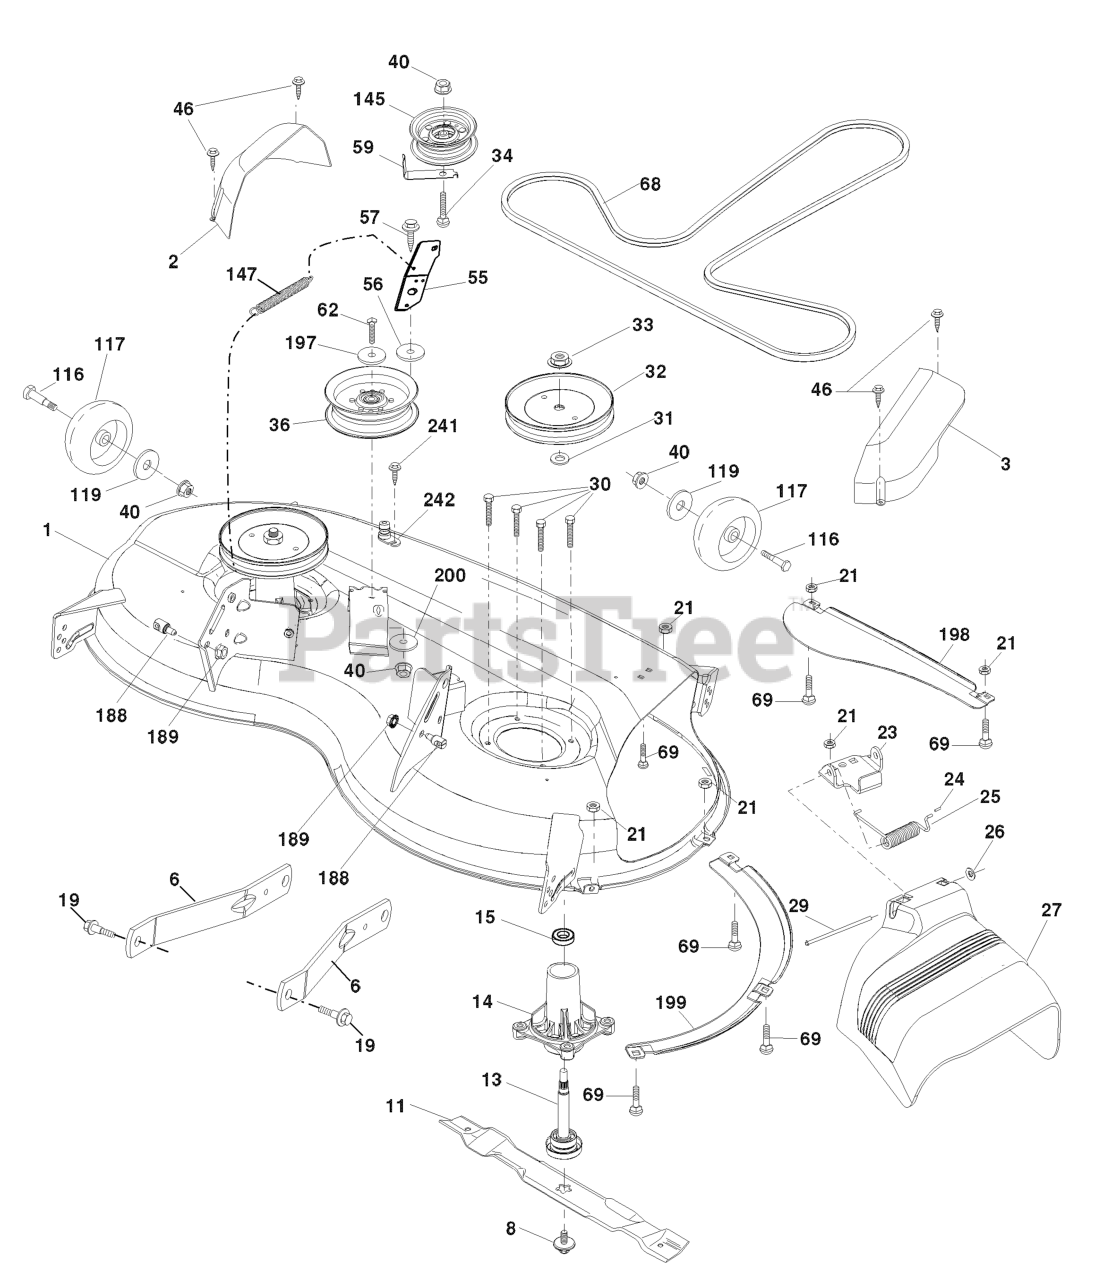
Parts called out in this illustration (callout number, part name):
1	DECK.WLDMT.W/TUBES.46"4GWB.422
2	COVER.MANDREL.RH.46"
3	COVER.MANDREL.LH.46"
6	ARM.SUSPENSION.MOWER.R
8	BOLT.WASHER.ASM.7/16-2
11	BLADE.MOWER.46".HI.LIFT
13	SHAFT.ASM.MDRL.N/GREASE.38
14	RP.HOUSING.MANDREL.4PT.
19	BOLT.SHOULDER
21	LOCKNUT
23	BRKT.DEFLECTOR.38"2005+
24	CAP-SLEEVE LT
25	SPRING.TORSION.DEFLECT
26	NUT PUSH M
27	SHIELD.DEFLECTOR.MOWER.46"BLAC
29	ROD.HINGE
30	SCREW, WASHER HEAD
31	WASHER.SPACER.MANDREL
32	PULLEY.MANDREL.5.438.PD
33	NUT.FLANGE.LOCK.TOP
34	BOLT.3/8-16X1.50
36	PULLEY.IDLER.2006
40	NUT LOCK FLG 3/8-16 UNC
46	SCREW.1/4-20X5/8
55	IDLER.ARM
56	SPACER.RETAINER
57	SCREW 3/8-16X1
59	GUARD, BELT
62	BOLT-HEX EAK
68	V-BELT
69	BOLT
116	BOLT.SHOULDER.3/8-16X3-5/8.
117	RP WHEEL. GUAGE RALLY
119	WASHER
145	PULLEY.IDLER.48"PRIMARY
147	SPRING.MOWER.DRIVE.ELECTRIC
188	STUD.FASTNER.W/ANTI-ROTATE
189	NUT LOCK HEX FLANGE 5/16-18
197	WASHER
198	BAFFLE CENTER FRONT
199	BAFFLE FRONT RH
200	Washer 13/32 x 2 x 10 Ga.
241	SCREW.TT.#10-32X.5.3/8.FLANGE
242	PORT.WASHOUT
